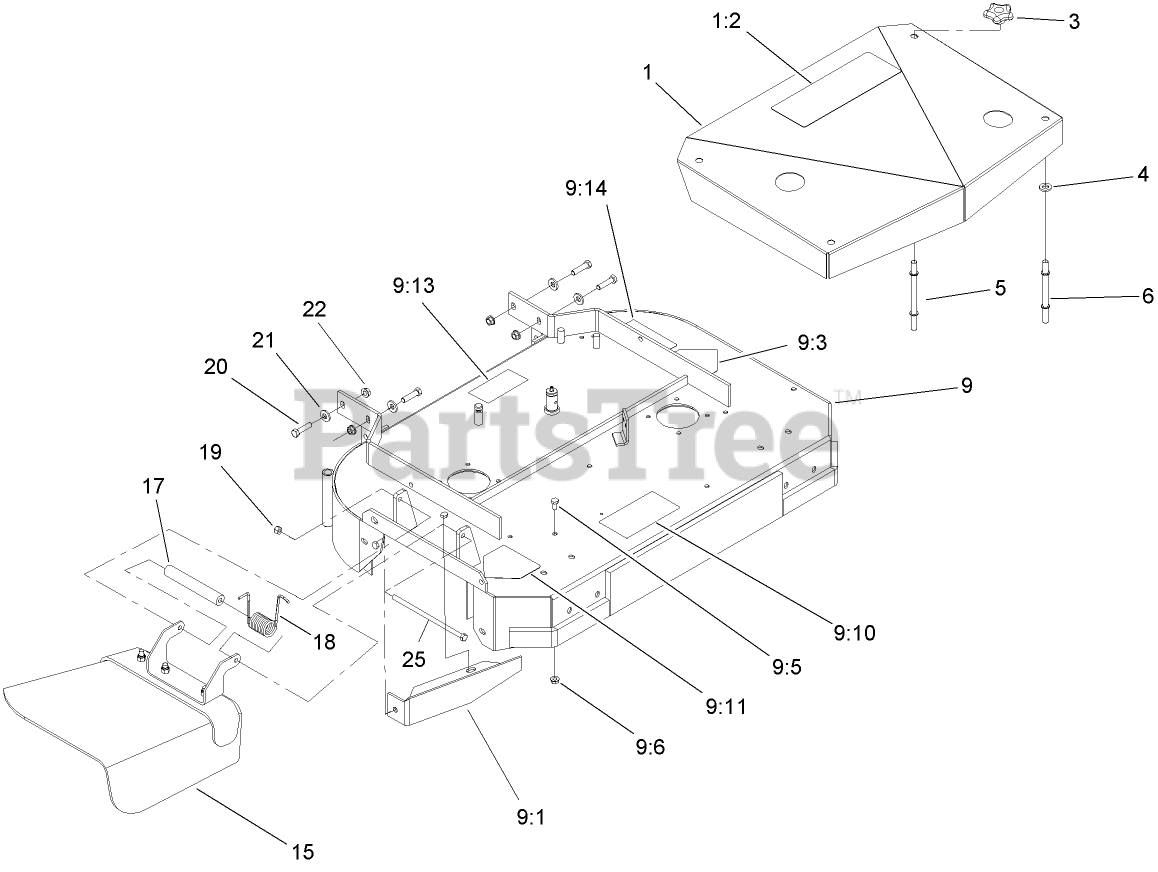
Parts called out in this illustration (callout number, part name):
1	SHIELD-BELT
3	KNOB-HANDLE
4	WASHER
5	STUD-SHIELD, BELT (LONG)
6	STUD-SHIELD, BELT (SHORT)
9	Deck ASM
9:1	BAFFLE-DOGLEG
9:3	DECAL-DANGER
9:5	SCREW-HH
9:6	NUT-HF
9:10	DECAL-DANGER, THROWN OBJECT
9:11	DECAL-DANGER
9:13	DECAL-ROUTING, BELT
9:14	DECAL-TORQUE, BOLT
15	DEFLECTOR ASM
17	SPACER
18	SPRING-TORSION
19	NUT-LOCK, NI
20	SCREW-HH
21	WASHER-BELLEVILLE
22	NUT-HHF, WHIZ
25	SCREW-HH
